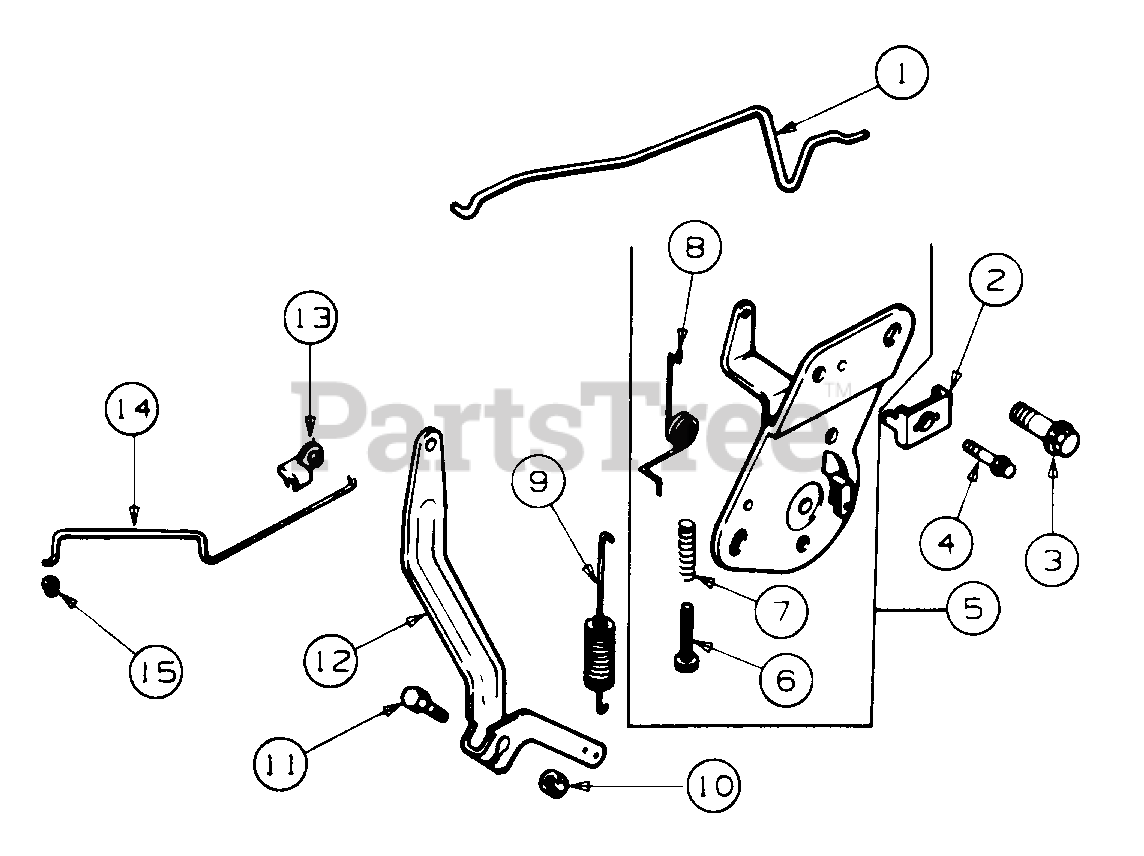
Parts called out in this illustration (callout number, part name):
1	Linkage, Choke
2	Clamp, Cable
3	Screw, Cable Clamp
4	Screw, Hex Hd, M6 X 1.0 X 16
5	Control, Speed Assy
7	Spring, Speed Control
8	Spring, Choke Return
9	Spring, Governor
10	Nut, Governor Arm, M6 X 1.0
11	Screw, Governor Arm, M6 X 1.0 X 25
12	Lever, Governor
14	Linkage, Throttle
